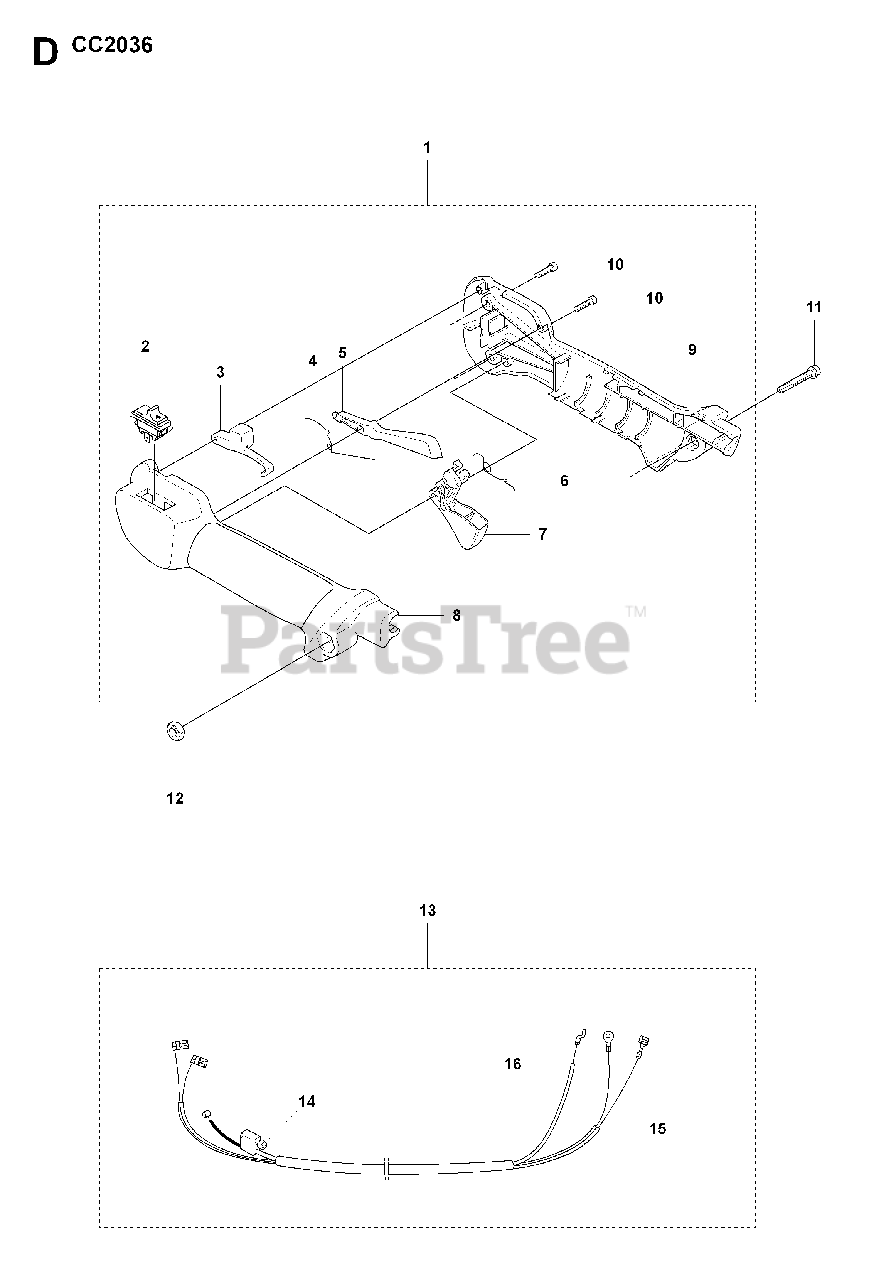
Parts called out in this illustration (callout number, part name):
1	TRIGGER HANDLE COMPLETE
2	START/STOP SWITCH
5	TRIGGER SAFETY
7	TRIGGER
8	HANDLE LEFT
9	HANDLE RIGHT
11	%SCREW
13	CABLE ASSY.
14	SCREW
15	SHORT CIRCUIT CABLE
16	THROTTLE CABLE
